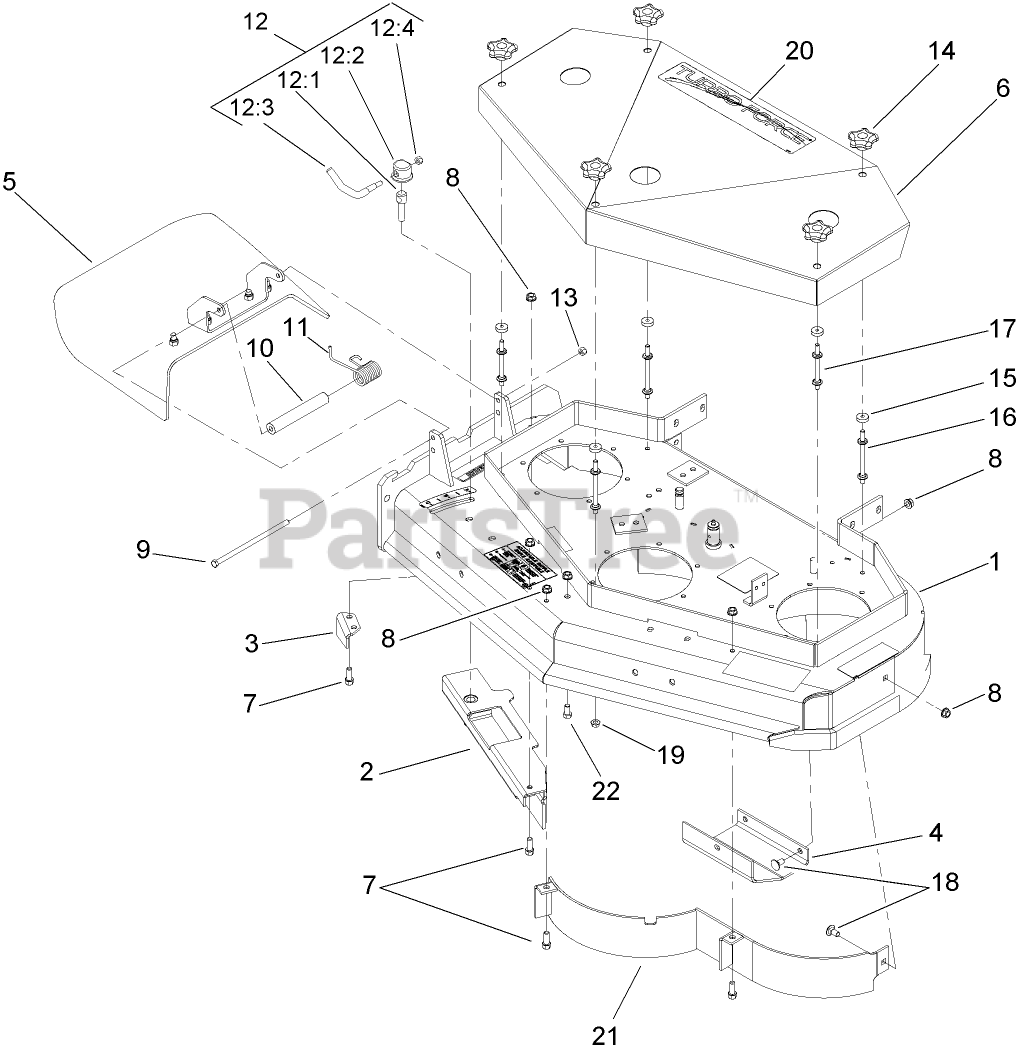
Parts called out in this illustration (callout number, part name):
1	DECK ASM
2	BAFFLE, ADJUST
3	BAFFLE-DISCHARGE
4	PLATE-SKID
5	DEFLECTOR ASM
6	COVER-DECK
7	SCREW-HWH
8	NUT-HHF, WHIZ
9	SCREW-HH
10	SPACER
11	SPRING-TORSION
12	LEVER ASM
12:1	Screw-Lock
12:2	CAP-LOCK
12:3	Lever-Lock
12:4	NUT-LOCK, NI
13	NUT-LOCK, NI
14	KNOB-HANDLE
15	WASHER
16	STUD-SHIELD, BELT (LONG)
17	STUD-SHIELD, BELT (SHORT)
18	SCREW-CARR
19	NUT-HF
20	DECAL
21	BAFFLE ASM
22	SCREW-HH
